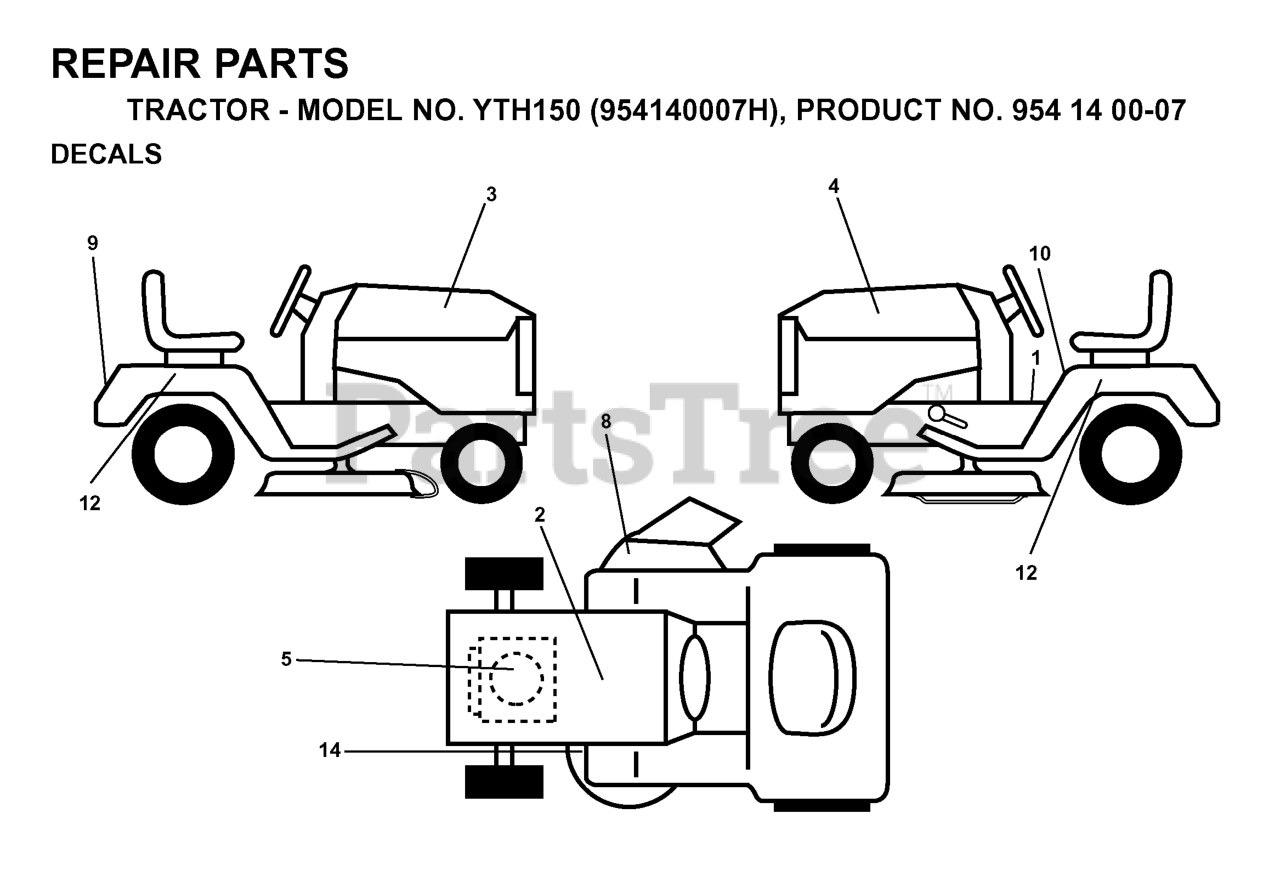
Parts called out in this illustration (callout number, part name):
2	DECAL BTRY SYMBOLS
3	DECAL, HOOD RH YTH150
4	DECAL, HOOD LH YTH150
8	DECAL WARNING (ENGLISH/FRENCH)
9	DECAL FENDER HUSQ
10	DECAL FENDER DANGER
14	DECAL V BELT SCHEMATIC
